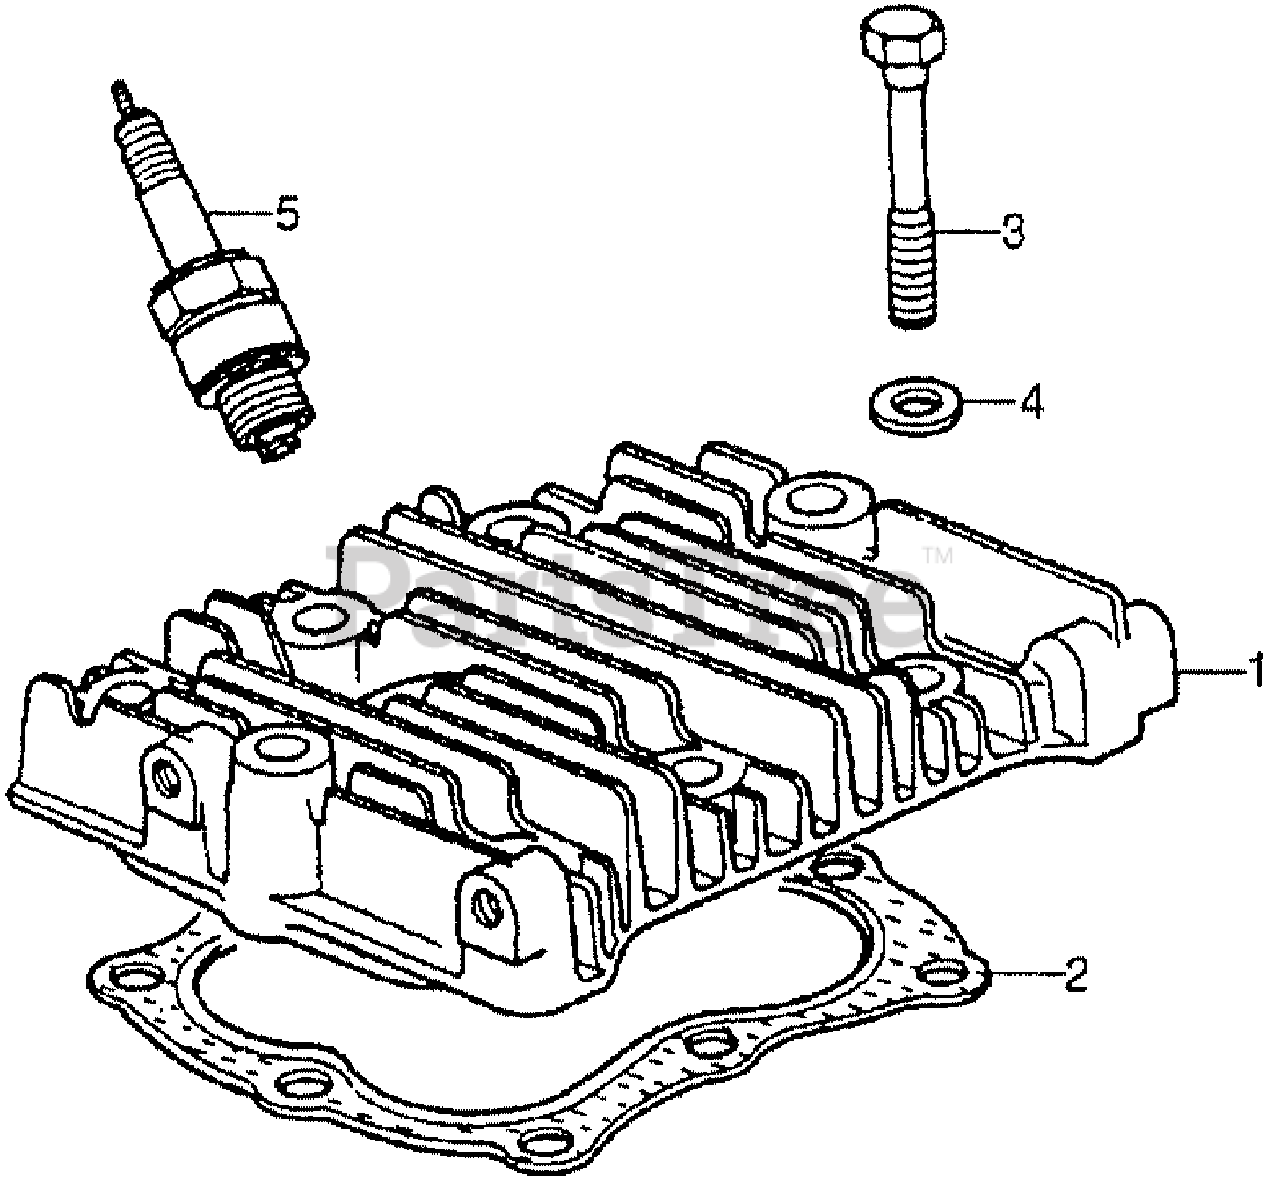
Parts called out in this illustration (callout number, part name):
1	CYLINDER HEAD
2	GASKET, CYLINDER HEAD (NOT AVAILABLE)
3	BOLT, HEX. (10X65)
4	WASHER, MAGNET FIXING
5	SPARK PLUG (B6HS) (NGK)
